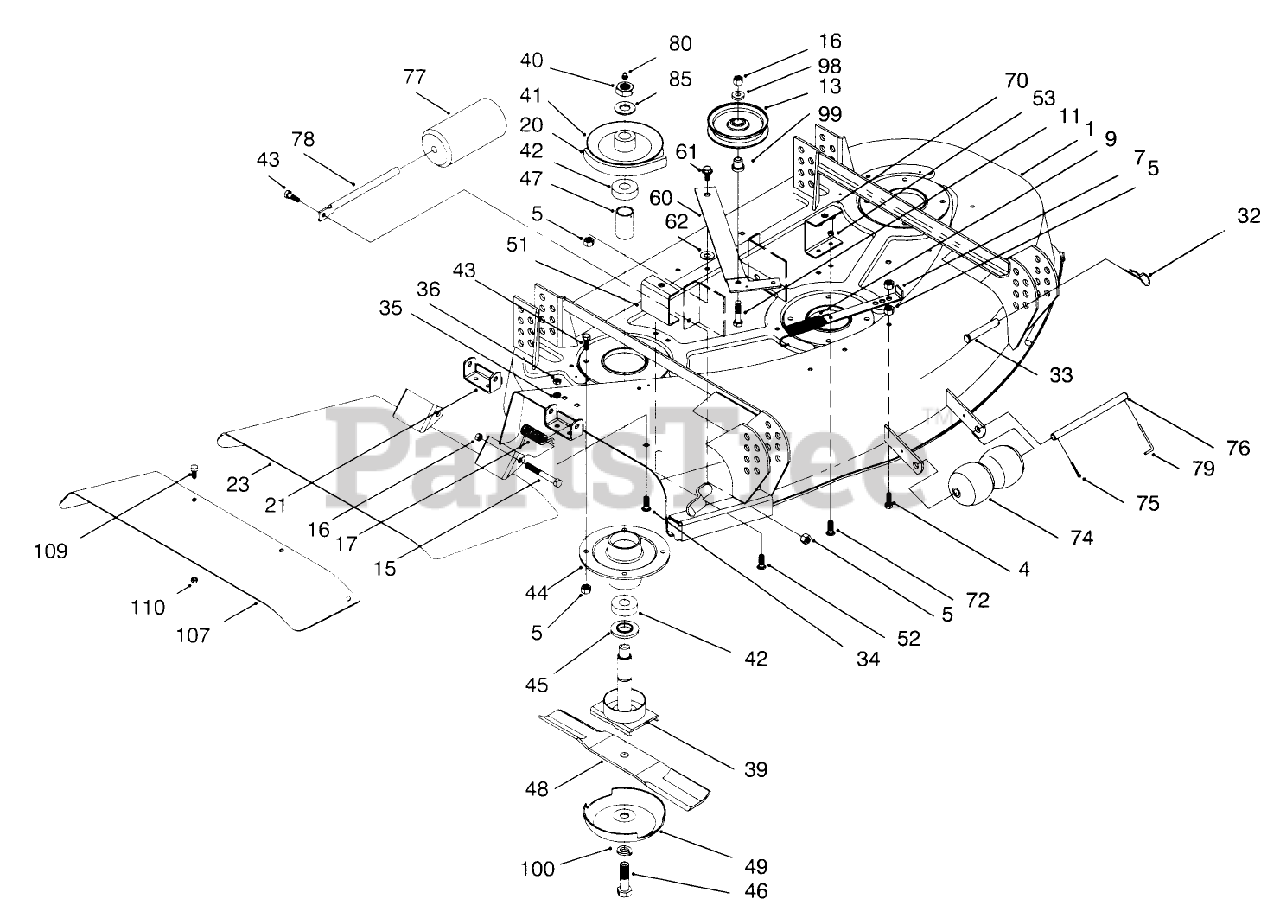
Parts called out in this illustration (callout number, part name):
4	SCREW-HH
5	NUT-LOCK, CONE
9	SPRING-EXTENSION, DECK
11	SCREW-HH
13	PULLEY-IDLER
15	SCREW-HH
16	NUT-HEX
17	SPRING
20	V-BELT-DECK
21	BRACKET-PIVOT
23	Grass Deflector
32	PIN-HAIR
33	PIN-CLEVIS
35	SCREW-HH
36	NUT-HEX
40	NUT-HEX
41	PULLEY-DECK
42	BEARING-BALL
43	SCREW-HH
44	HOUSING-SPINDLE
45	SPACER-SPINDLE
46	SCREW-BLADE
47	SPACER-BEARING
52	SCREW-CARR
53	NUT-LOCK, NI
61	SCREW-SHOULDER
62	WASHER
72	SCREW-CARR
74	ROLLER
75	PIN-COTTER
76	SHAFT-ROLLER
77	ROLLER-DECK
78	ROD-ROLLER
79	PIN-SPECIAL
80	FITTING-GREASE
85	WASHER
98	WASHER-FLAT
99	BUSHING-PULLEY
100	WASHER-LOCK
109	SCREW-HH
110	NUT-LOCK, NI
